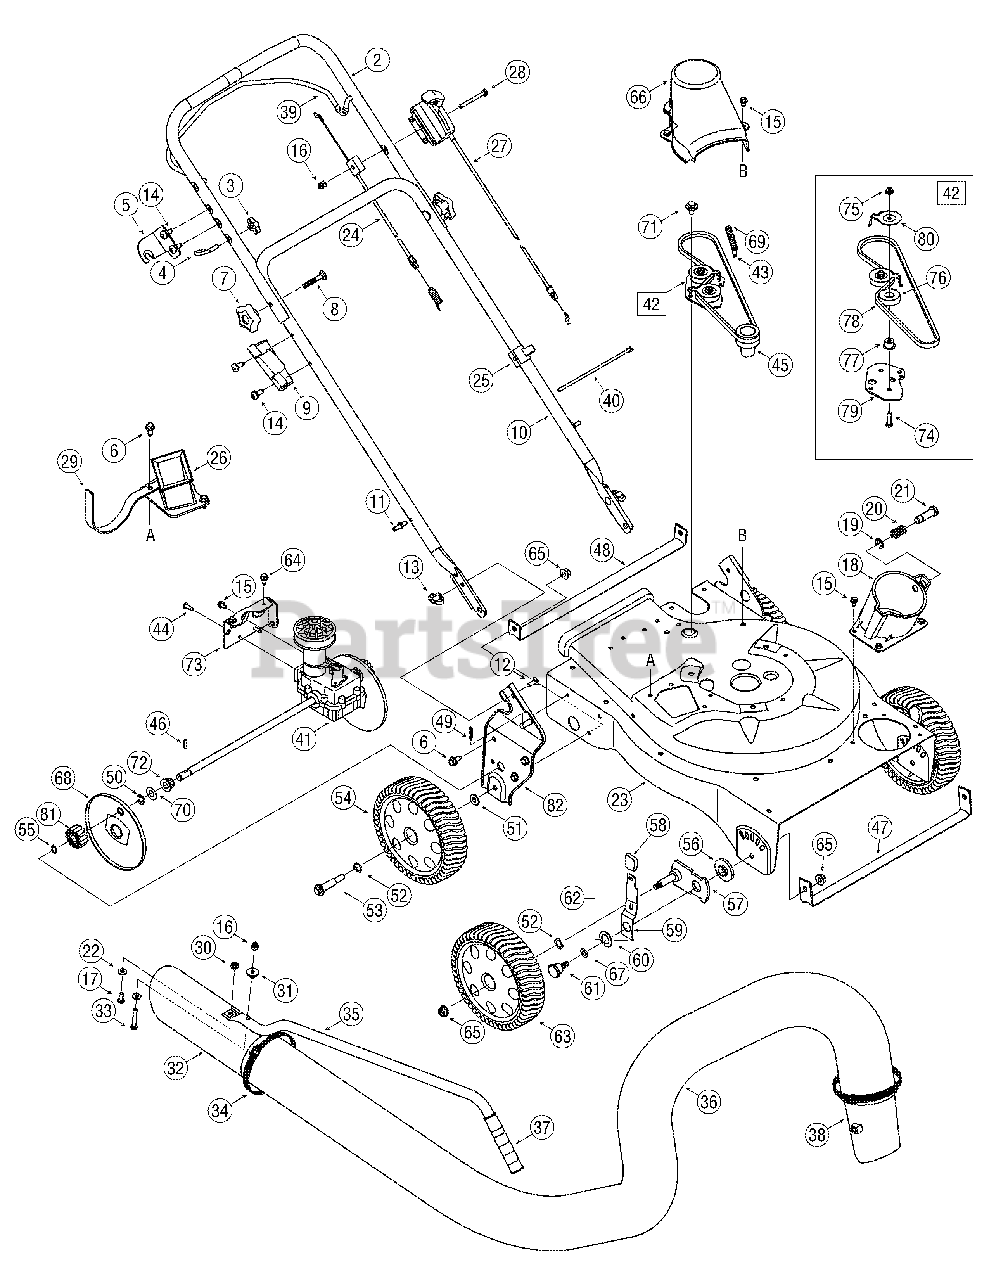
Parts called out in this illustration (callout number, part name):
1	Saddle Washer, .320 x.93
6	Hex Cap Screw 5/16-12 x.750
7	Star Knob
8	Carriage Bolt
9	Nozzle Handle Clip
12	Carriage Screw 1/4-20 x.75
13	Wing Nut 1/4-20
14	TT Screw, 5/16-18 x .750
15	Screw, 1/4-20 x .500
16	Cap Lock Nut, 1/4-20
17	Hex Cap Screw 1/4-20 x.620
18	Hose Base Adapter Assembly (Incl. Ref.# 19-21)
19	E Ring.500 Dia
20	Compression Spring
21	Clevis Pin
22	Flat Washer.271 ID x.630 OD
25	Cable Guide
27	Speed Control Cable
28	Hex Screw, 1/4-20 x 2.50
32	Hose Nozzle
33	Hex Cap Screw 1/4-20 x 2.625
34	Adjustment Clamp
36	Vacuum Hose
37	Handle Grip
38	Hose Adapter
39	Drive Control
40	Cable Tie
41	Transmission Assembly
42	Idler Assembly (Incl. Ref.# 74-80)
43	Shoulder Screw, #12-24 x .30 x .46
44	Screw, #12-16 x .750
45	Impeller Hub
46	Dowel Pin
49	Cotter Pin
50	E-Ring
51	Flat Washer, .385 x 1.00 x .135
52	Wave Washer.531 ID x.781 OD
53	Shoulder Screw 3/8-16
54	Wheel, 8 x 2.125
55	Snap Ring
56	Height Adjustment Bearing
57	Pivot Arm Assembly
58	Height Adjustment Knob
59	Spring Lever
60	Bell Washer.760 ID x.25 OD
61	Shoulder Screw,.750 x.500
62	Height Lever Assembly (Incl. Ref.# 58-59)
63	Wheel 8 x 2
64	Screw, 1/4-20 x .625
65	Flange Lock Nut, 3/8-16
66	Belt Cover
67	Thrust Washer.375 ID x.70 OD
68	Wheel Cover
69	Extension Spring,.375 x 2.95
70	Flat Washer,.508ID x1.00OD x.020
71	Shoulder Screw,.560 x.165
72	Drive Axle Bushing
74	Screw, 1/4-20 x 1.00
75	Flange Lock Nut, 1/4-20
76	Ball Bearing
77	Flange Spacer,.260 x.659 x.517
78	Belt, 3/8 x 32.5
80	Belt Keeper
81	Spur Gear - RH
